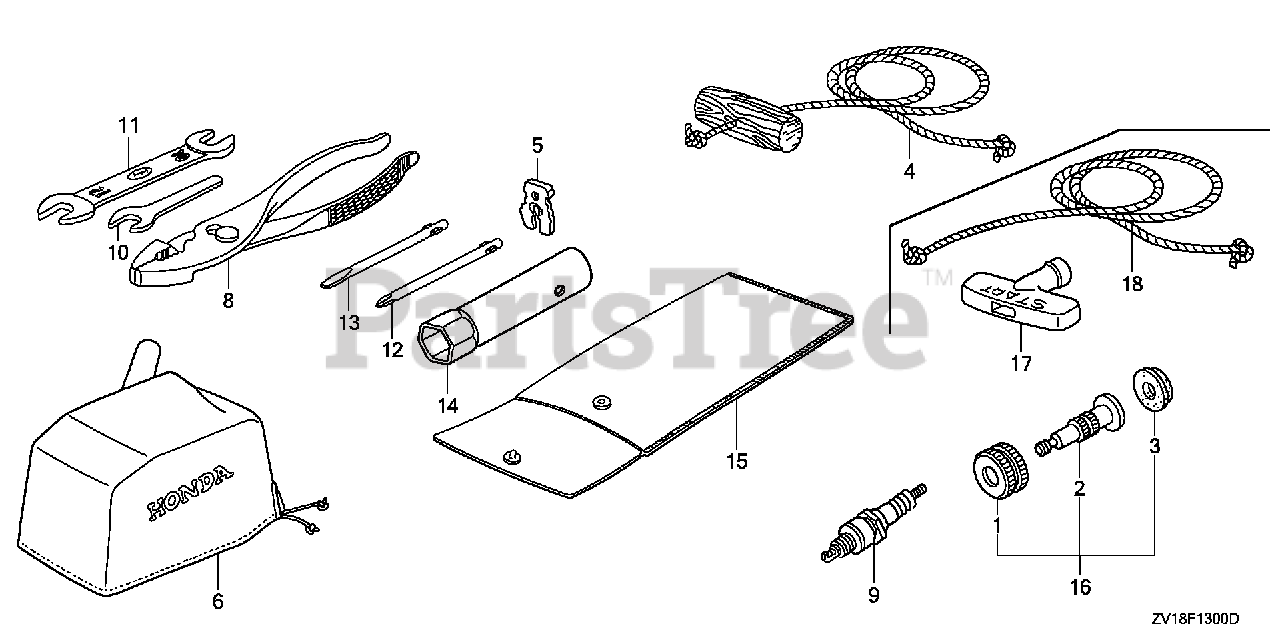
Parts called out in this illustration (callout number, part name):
1	NUT, WATER MOUTH
2	JOINT, WATER HOSE
3	SEAT, WATER MOUTH
5	CLIP, EMERGENCY LOCK
6	COVER, BODY
8	PLIERS (135) (RIKEN)
9	SPARK PLUG (W16EPR-U)
9	SPARK PLUG (BPR5ES) (NGK)
9	SPARK PLUG (W16EPR-U) (DENSO)
10	SPANNER, 8
11	SPANNER (10X12)
12	DRIVER 1, PLUS SCREW (NO.2)
13	DRIVER 3, MINUS SCREW (NO.2)
14	WRENCH, BOX (P21)
15	BAG, TOOL (160MM)
17	GRIP, STARTER
17	KNOB, RECOIL SRARTER
18	ROPE, RECOIL STARTER (1300MM)
